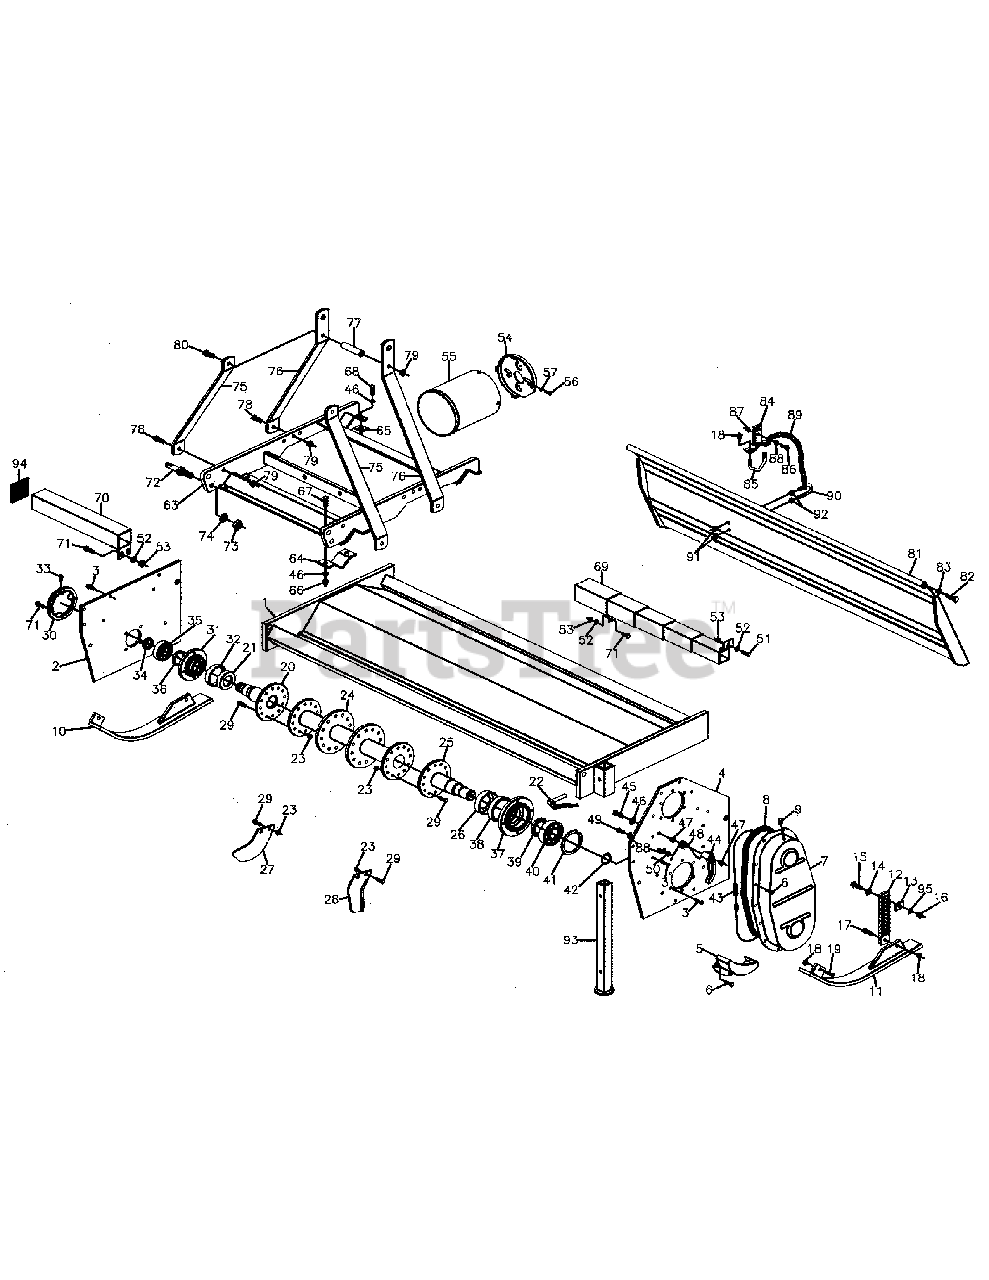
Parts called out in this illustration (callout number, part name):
1	Frame 74"
2	Right side panel
3	Hex bolt M10x25
4	Drive panel
5	Chain case cover protection
6	Hex bolt M10x30
7	Chain case cover
8	Gasket
9	Breather cap
10	Right skid
11	Left skid
12	Serrated adjustment arm
13	Plate
14	Threaded washer
15	Hex bolt M12x60
16	Nut M12
17	Hex bolt M12x40
18	Nut M12
19	Hex bolt M12x30
20	Right flanged pivot
21	Dirt shield
22	Cotter pin Ø10x70
23	Nut M12
25	Left flanged pivot
26	Dirt shield
27	Right C blade
28	Left C blade
29	Hex bolt M12x35
30	Right outer cover
31	Complete right support
32	Dirt shield
33	Grease fitting
34	Safety nut M35x1.5
35	Bearing 6307
36	Oil seal 45.60.10
37	Left rotor support
39	Oil seal 55.80.10
40	Bearing 6309
41	Inner snap ring Ø100
42	Outer snap ring Ø45
43	Chain ASA 100x36
44	Chain tensioner
45	Hex bolt M14x75
46	Lock washer Ø14
47	Nut M14
48	Spring
49	Hex bolt M10x65
50	Nut M10
51	Hex bolt M10x40
52	Flat washer Ø10
53	Nut M10
54	Protection support
55	PTO shaft protection
56	Bolt TC M6x12
57	Flat washer Ø6
63	3 point hitch side shift
64	Plate
65	Plate
66	Nut M14
67	Hex bolt M14x45
68	Hex bolt M14x40
69	Protection 74"
70	Right protection 74"
71	Hex bolt M10x35
72	Hitch pin
73	Nut M20
74	Lock washer Ø20
75	Top hitch support
76	Top hitch arm
77	Spacer
78	Hex bolt M14x45
79	Nut M14
80	Hex bolt M14x110
81	Tail gate 74"
82	Hex bolt M18x80
83	Nut M18
84	Chain hitch
85	U bolt
86	Hex bolt M10x30
87	Nut M10
88	Flat washer Ø10
90	U bolt
91	Nut M8
92	Nut M8
